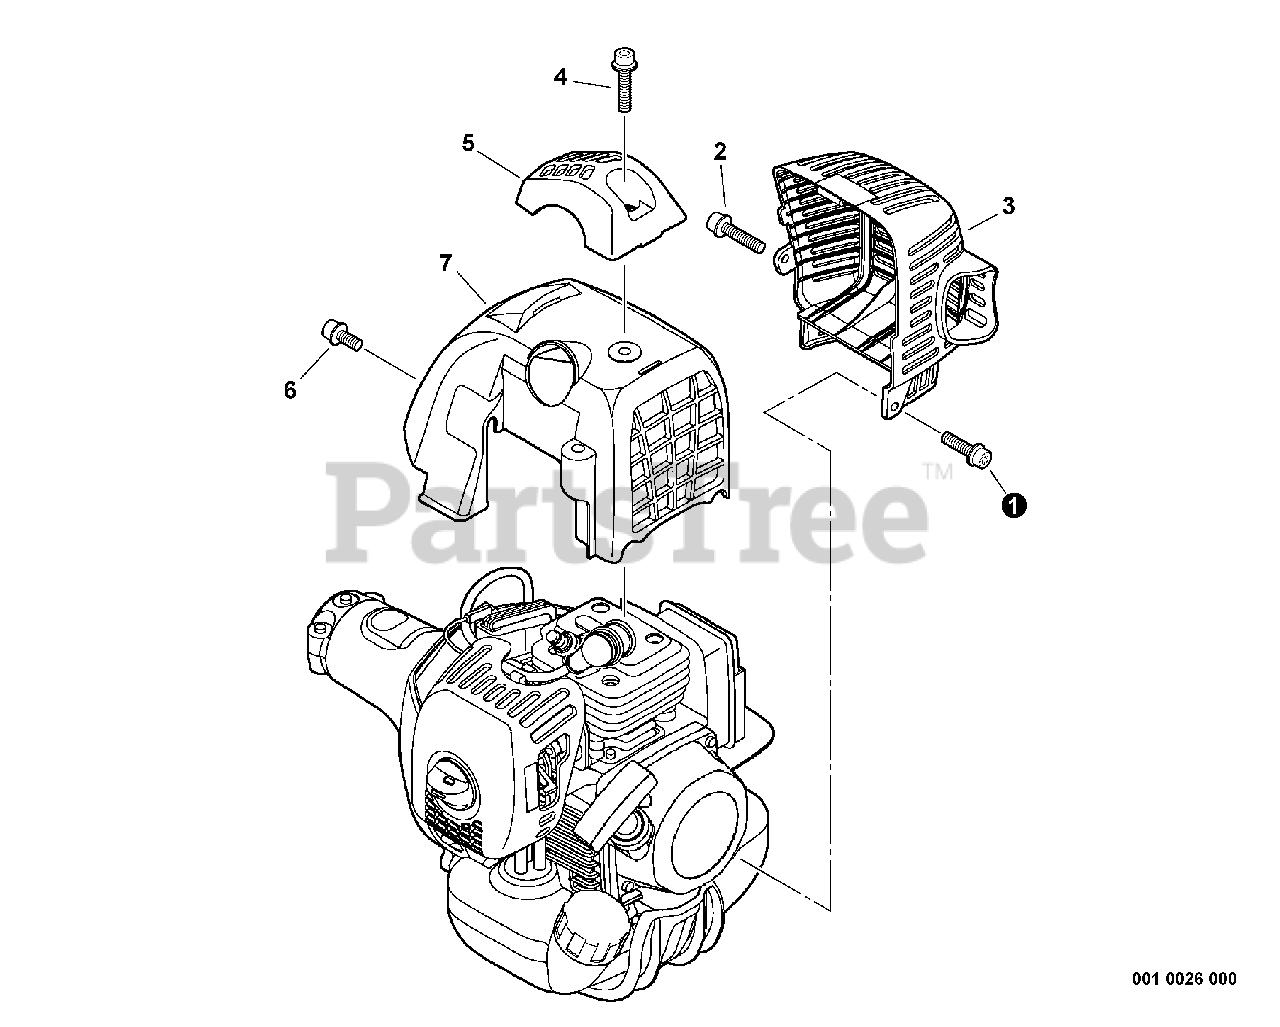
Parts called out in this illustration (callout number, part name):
1	SCREW - 5X16
2	SCREW - 5X20
3	COVER, EXHAUST
4	SCREW - 5X20
5	GUARD - TOP
6	SCREW - 5X10
7	COVER, ENGINE
